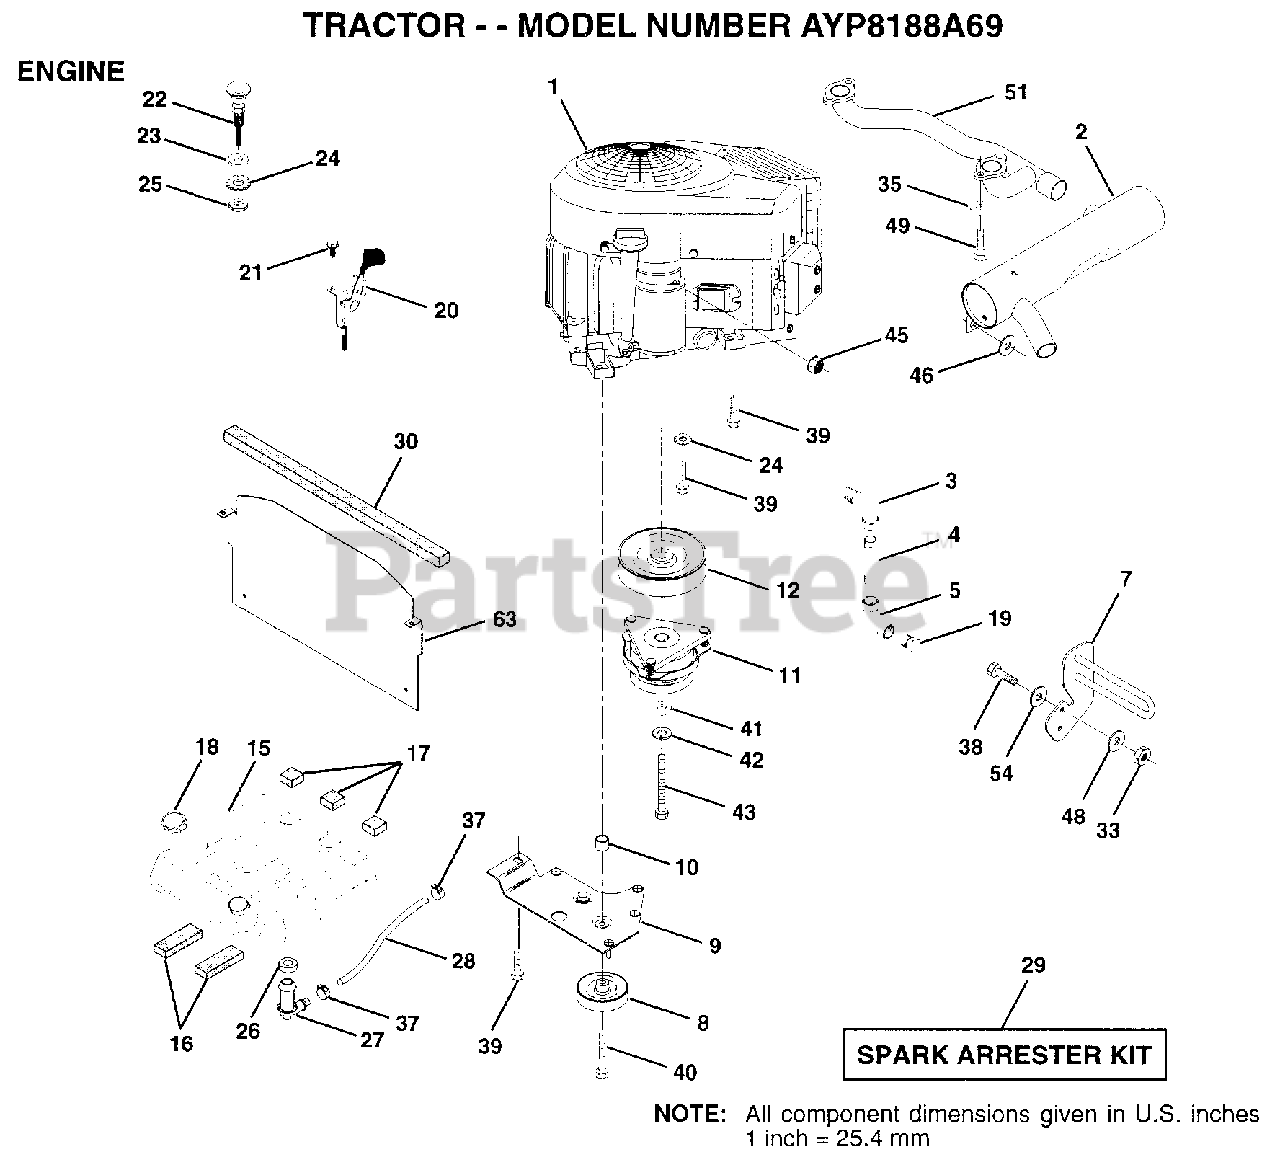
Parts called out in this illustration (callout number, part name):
3	STREET ELBOW LT
4	PIPE NIPPLE
5	ELBOW
10	BUSHING.
12	PULLEY.ENGINE.VGT
16	PAD IDLER TI
17	PAD-SPACER LT
18	CAP ASM FUEL
19	PLUG T
21	SCREW LT
23	WASHER
24	LOCKWASHER
25	"NUT,KEPS 3/8-24IM"
26	BUSHING OUTLET T
27	STEM.TANK.FUEL
29	SPARK ARREST KIT
30	FOAM-STRIP LT
33	NUT
35	LOCKWASHER
37	HOSE CLAMP
38	"BOLT,HEX"
39	SCREW LT
40	SCREW.3/8-16X3.25
41	WASHER
42	LOCKWASHER
43	BOLT.7/16-20X4.25
45	NUT
46	WASHER HYT
48	WASHER T
49	BOLT.HD.SOCKET.
51	PIPE.EXHAUST.B&S
54	WASHER
63	SHIELD.HEAT.VGT.
